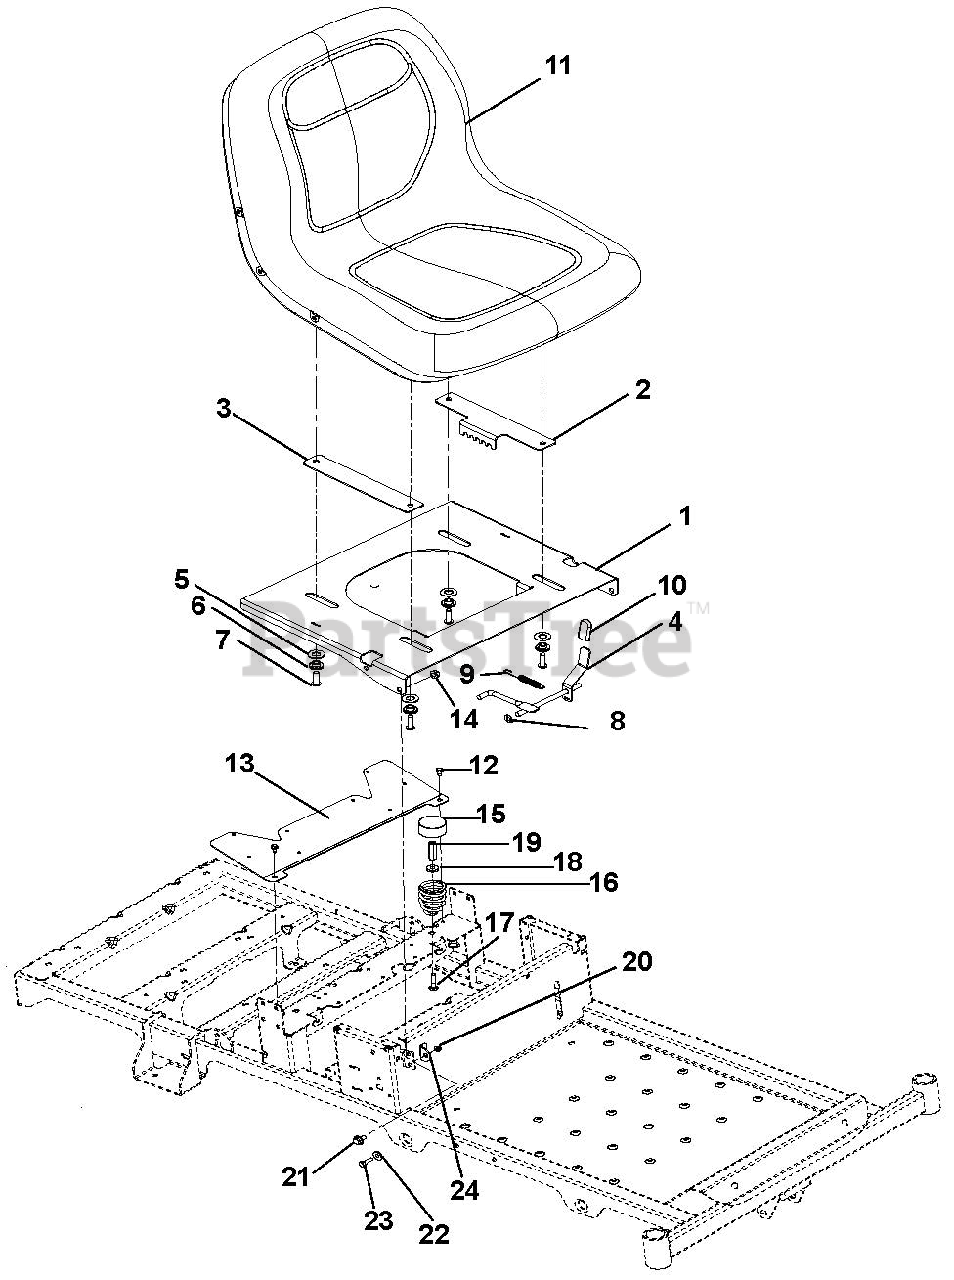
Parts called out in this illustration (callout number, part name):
1	PLATE, SEAT, ADJUSTABLE
2	PLATE, ADJUSTABLE SEAT TRACK
3	PLATE, ADJUSTABLE SEAT SLIDE
4	WLDMT, ADJUSTABLE SEAT LATCH
5	WSHR-FL-STL .505X1.00X.062YWZC
6	BSHG-FLG .32X.500X.344X.880
7	SCR-SKH .31-18X1.0 BTNHD YWZC
8	NUT-PUSH .312
9	SG-TENS .043X.44X3.31 WLD 5.8
10	GRIP, SEAT LEVER, GREY
11	SEAT, MILSCO XB180 GRAY
12	@SCR-TAP .25-20X.50 HWH TR YWZ
13	GUARD, FAN
14	@NUT-LK-TOP-FLG .38-16 YWZC
15	HUB CAP
16	SPRING, SEAT
17	@BLT-RDHDSQNK .31-18X1.50 G5YZ
18	WSHR-FL-STL .328X.87X.179 YWZC
19	NUT, COUPLING 5/16-18 X 1 3/4
20	@NUT-LK-NYL-FLG .31-18 YWZC
21	BOLT-SHLDR .375-16X.150
22	BSHG, FLG .325X.499X.26X.88
23	@BLT-HEX .31-18X1.00 GR5 YWZC
24	BRKT, SEAT STOP
